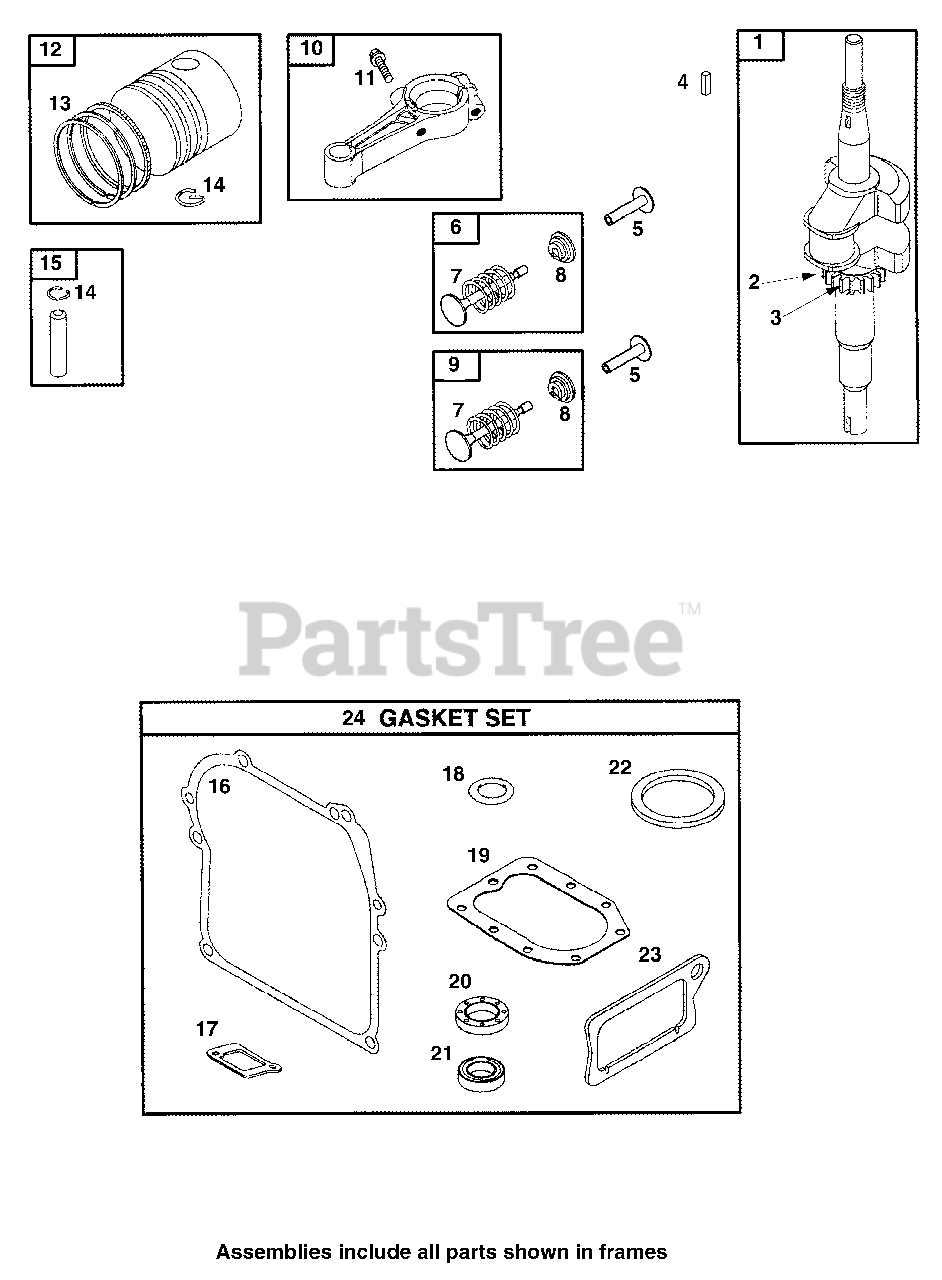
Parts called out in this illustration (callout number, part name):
1	Crankshaft
2	Timing Gear
3	Timing Pin
4	Flywheel Key
5	Valve Tappet
6	Intake Valve
7	Valve Spring
8	Valve Retainer
9	Exhaust Valve
10	Connecting Rod
11	Connecting Rod Screw
12	Piston Assembly
13	Ring Set (Standard)
14	Piston Pin Lock
15	Piston Pin (Standard)
16	Crankcase Gasket
17	Intake Gasket
18	O-Ring Seal
19	Cylinder Head Gasket
20	Oil Seal
21	Oil Seal
22	Air Cleaner Gasket
23	Breather Gasket
24	Gasket Set
